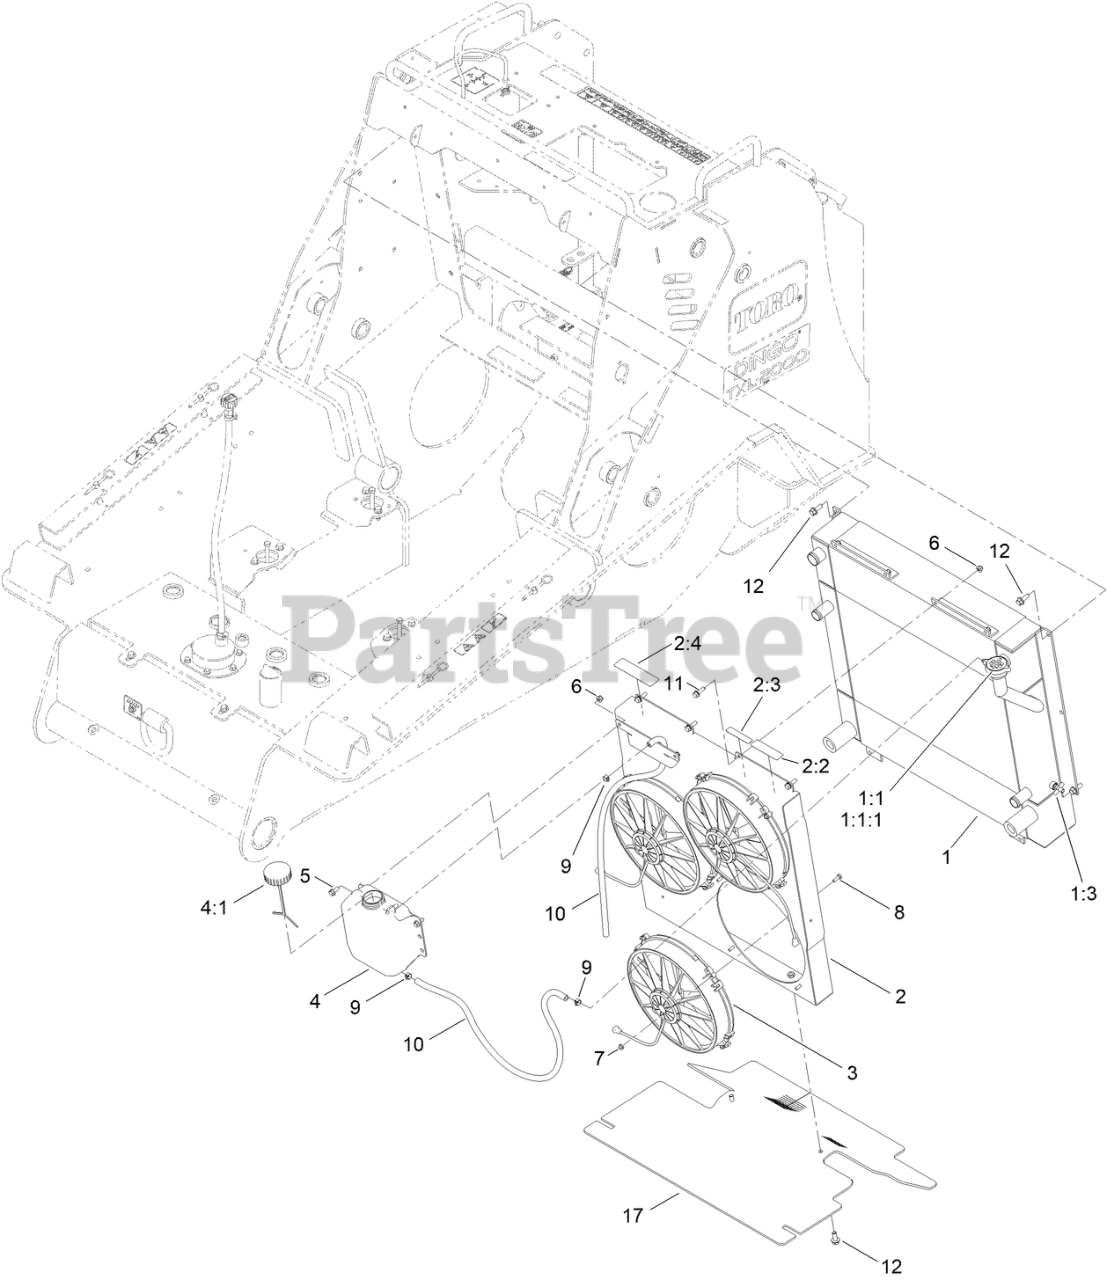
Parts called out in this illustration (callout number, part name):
1	RADIATOR/COOLER ASM
1:1	CAP-RADIATOR
1:1:1	DECAL-CAP, RADIATOR
1:3	DRAINCOCK
2	COOLER SHROUD ASM
2:2	DECAL-RADIATOR FILL
2:3	DECAL-WARNING, FAN
2:4	DECAL-DANGER
4	RESERVOIR-COOLANT ASM
4:1	CAP-RESERVOIR
5	SCREW-HHF
6	NUT-HF, NI
7	NUT-HF
8	SCREW-HH
9	CLAMP-HOSE
10	HOSE-FUEL
11	SCREW-HHF
12	SCREW-HHF
17	BAFFLE
